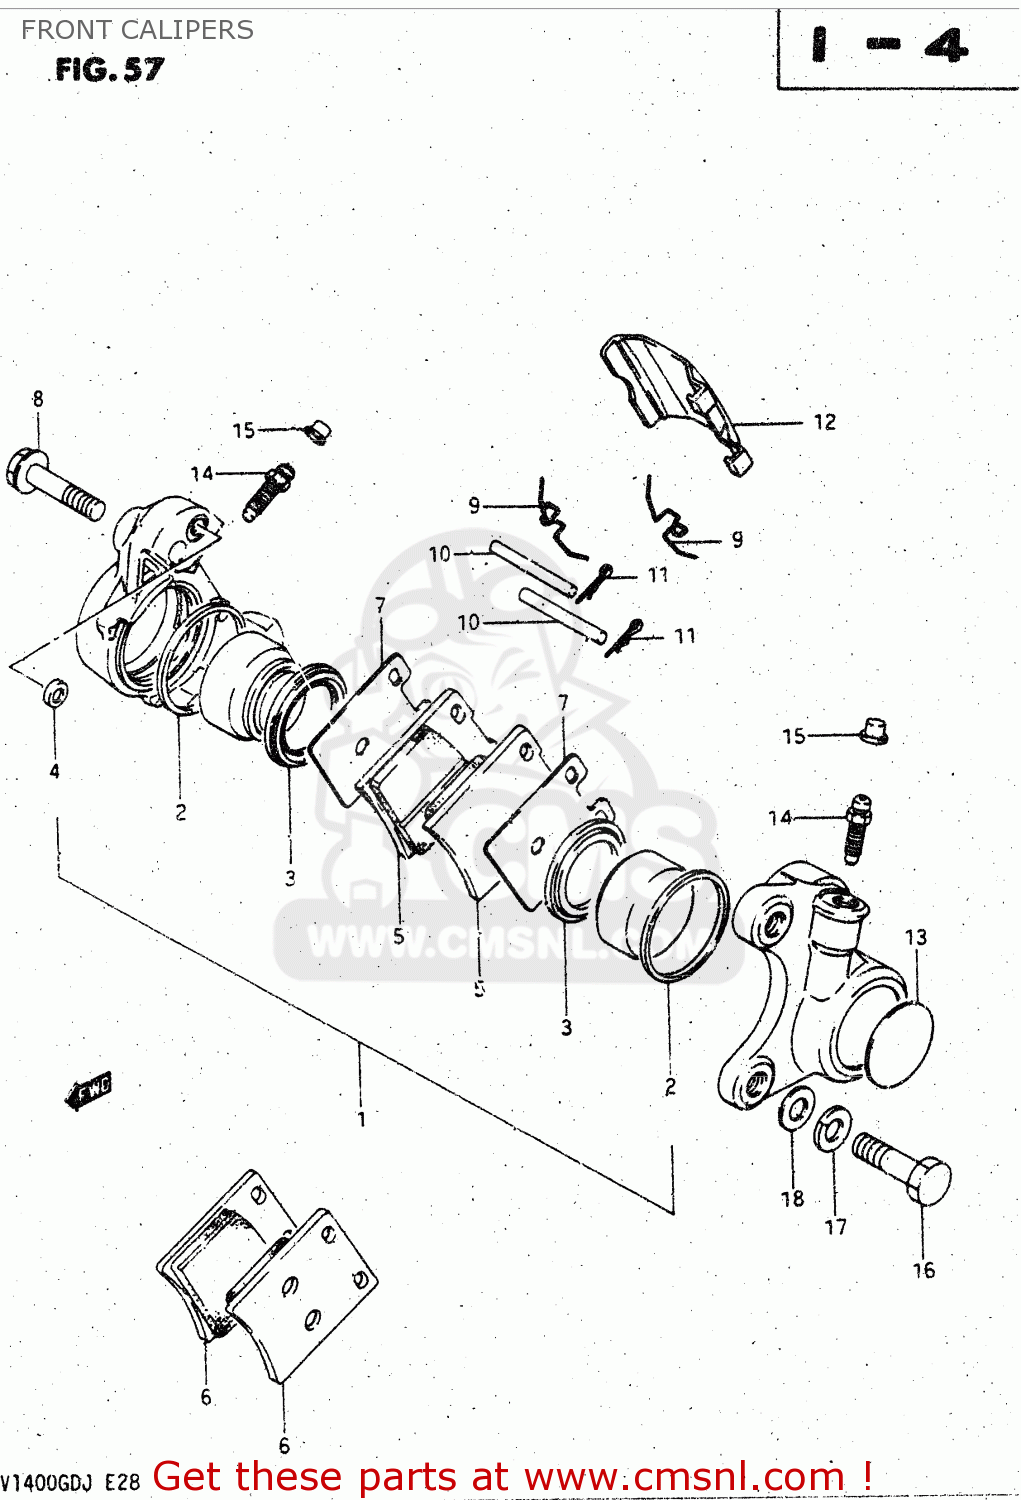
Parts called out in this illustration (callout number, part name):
1	PISTON SET
2	SEAL,FR CALIPE
3	BOOT,PISTON
4	SEAL,JOINT
5	PAD
6	PAD
7	SHIM,PAD
8	BOLT,HOUSING
9	BOLT,HOUSING
10	PIN,PAD
11	CLIP,PAD PIN
12	COVER
13	CAP,CALIPER
14	BLEEDER
15	CAP,BREATHER
16	BOLT(10X38)
17	WASHER,LOCK,10
18	WASHER
